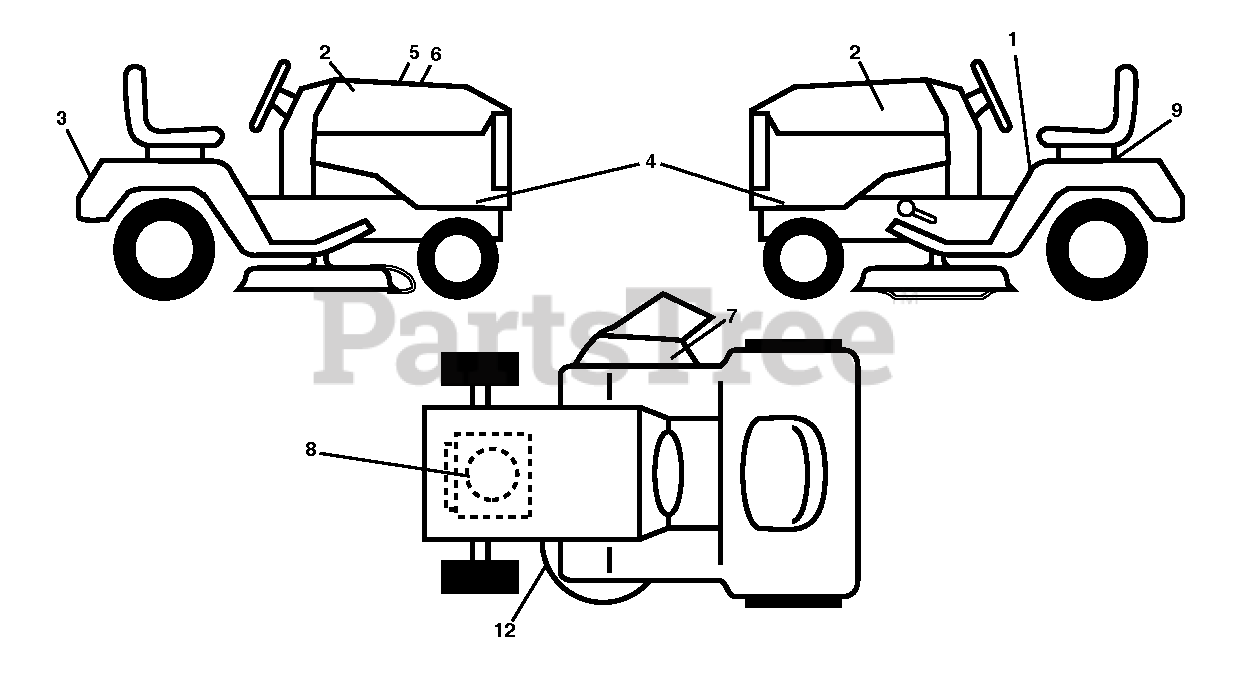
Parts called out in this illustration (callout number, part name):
1	DECAL.WARN.STARTINST.LOWEARIEN
2	DECAL.BADGE.170MM.TEXTLOGO.
3	DECAL.FENDER
4	DECAL.SDPNL.YTA18542.SET.HUSQ
5	DECAL.WARNING.CUST.RESP.E85.
6	DECAL.RPL.BSM33.INTK.TLW.42
7	DECAL, DECK DEFLECTOR, WARNING
8	DECAL.ENG.BS.18.5INTK.381713
9	DECAL BTRY SYMBOLS
12	DECAL.V-BELT.SCH.42/46"MEC/ELE
